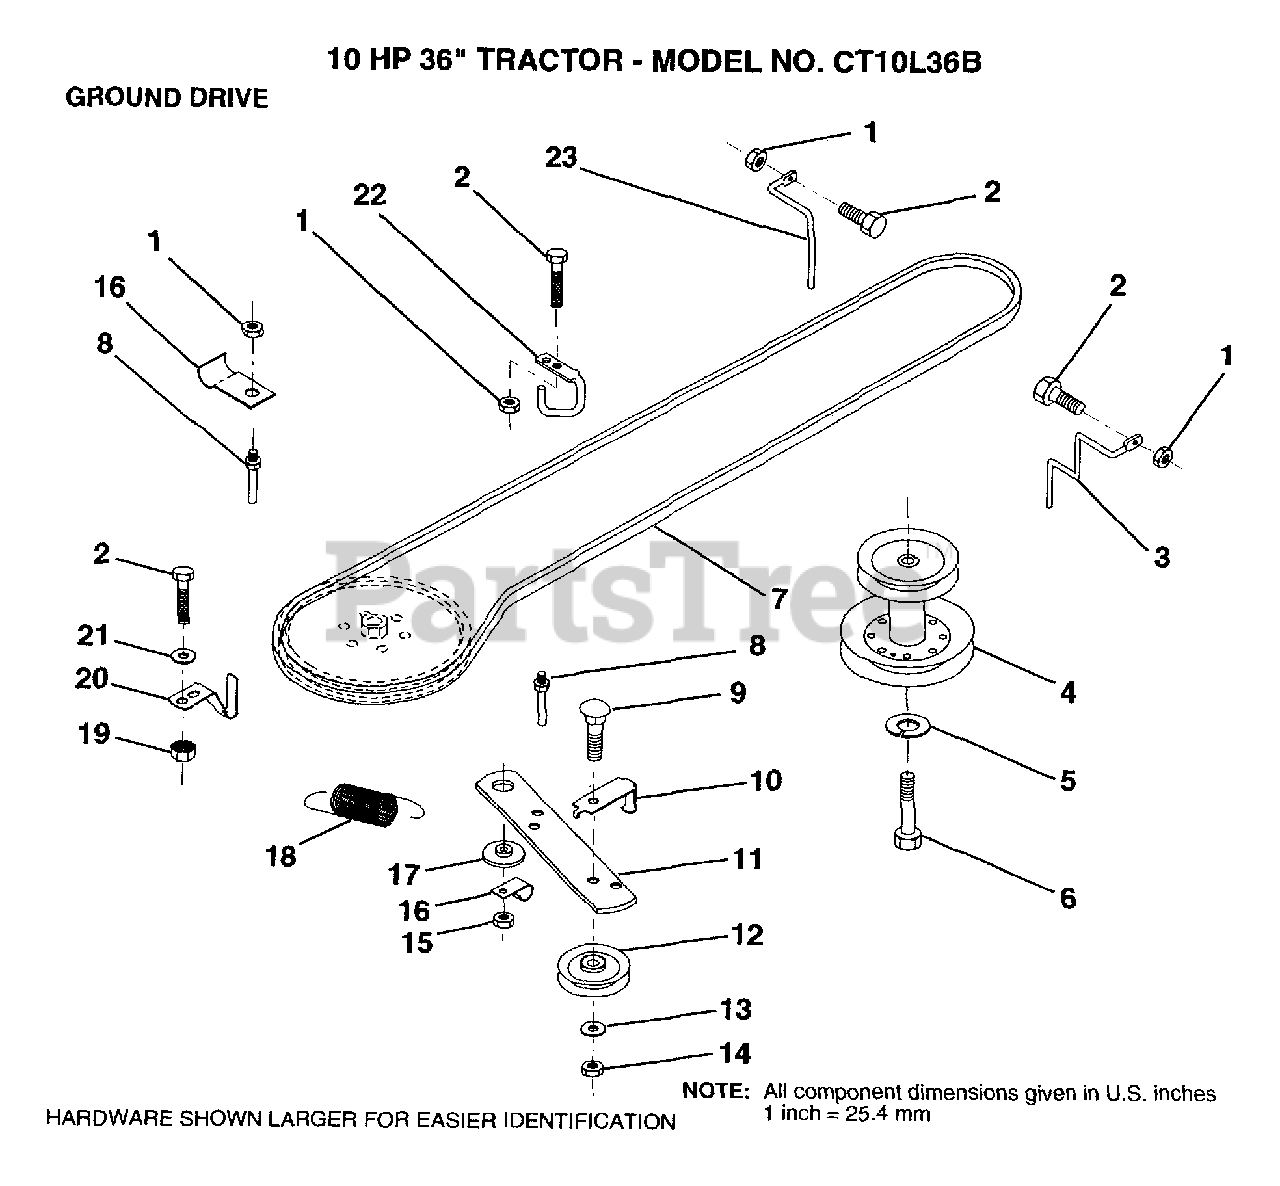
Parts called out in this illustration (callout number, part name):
2	BOLT
5	LOCKWASHER
6	HEX BOLT
7	BELT
8	"KEEPER,DRIVE BELT"
9	BOLT
10	"KEEP,IDLER DR BEL"
13	WASHER
14	LOCKNUT
16	"CLIP,INSULATOR"
17	SPACER RETAINER
20	"KEEPER,DR BELT "
21	WASHER
22	"KEEPER,FRA DR BEL"
